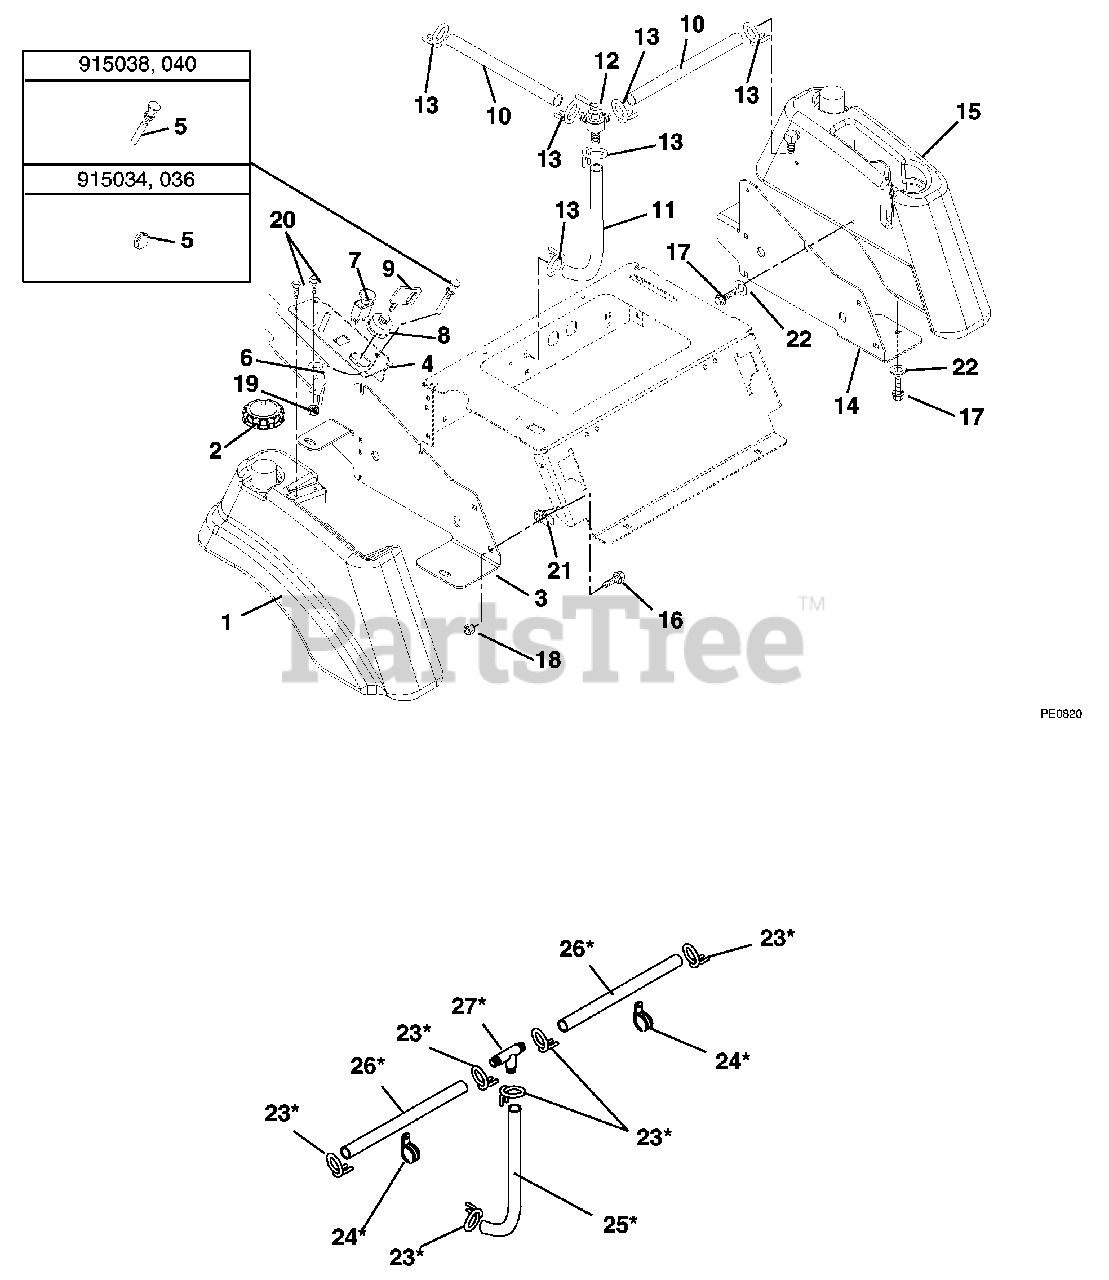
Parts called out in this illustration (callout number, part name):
1	Tank, Fuel - Right Hand
2	Fuel Cap
3	Seat Plate/Tank Support Right Hand
4	Bracket, Control
5	Choke Cable(038, 040)
5	Hole Plug, Plastic .44 Hole (034, 036)
6	Throttle Cable (038, 040)
6	Throttle Cable (034, 036)
7	Switch, Clutch
8	Key Switch
9	Key with Cap
10	Gas Line, Bulk .25 I.D. x 22 Long
11	Gas Line, Bulk .25 I.D. x 14 Long (038, 040)
11	Gas Line, Bulk .25 I.D. x 5.5 Long (034, 036)
12	Valve, Fuel
13	Clamp, Hose Wire .49/.51 x .116
14	Seat Plate Left Hand
15	Tank, Fuel - Left Hand
16	Bolt, Round Head Square Neck .38-16 x .75 Grade 5
17	Bolt, Serrated Hex Flange Washer Head .312-18 x .75
18	Nut, Locking Top Flange .38-16
19	Nut, Locking Nylon 10-24 with Insert
20	Screw, Machine 10-24 x .50 Hex Washer Head
21	Retainer .38 Push-On
22	Washer, Flat Steel .328 x 1.00 x .094
23	Clamp, Hose Wire .49/.51 x .116
24	Clamp, Cushioned Steel
25	Gas Line, Bulk .25 I.D. x 14 Long (038, 040)
25	Gas Line, Bulk .25 I.D. x 5.5 Long (034, 036)
26	Gas Line, Bulk .25 I.D. x 22 Long
27	T-Fitting
NS	Fuel Fitting Bushing
